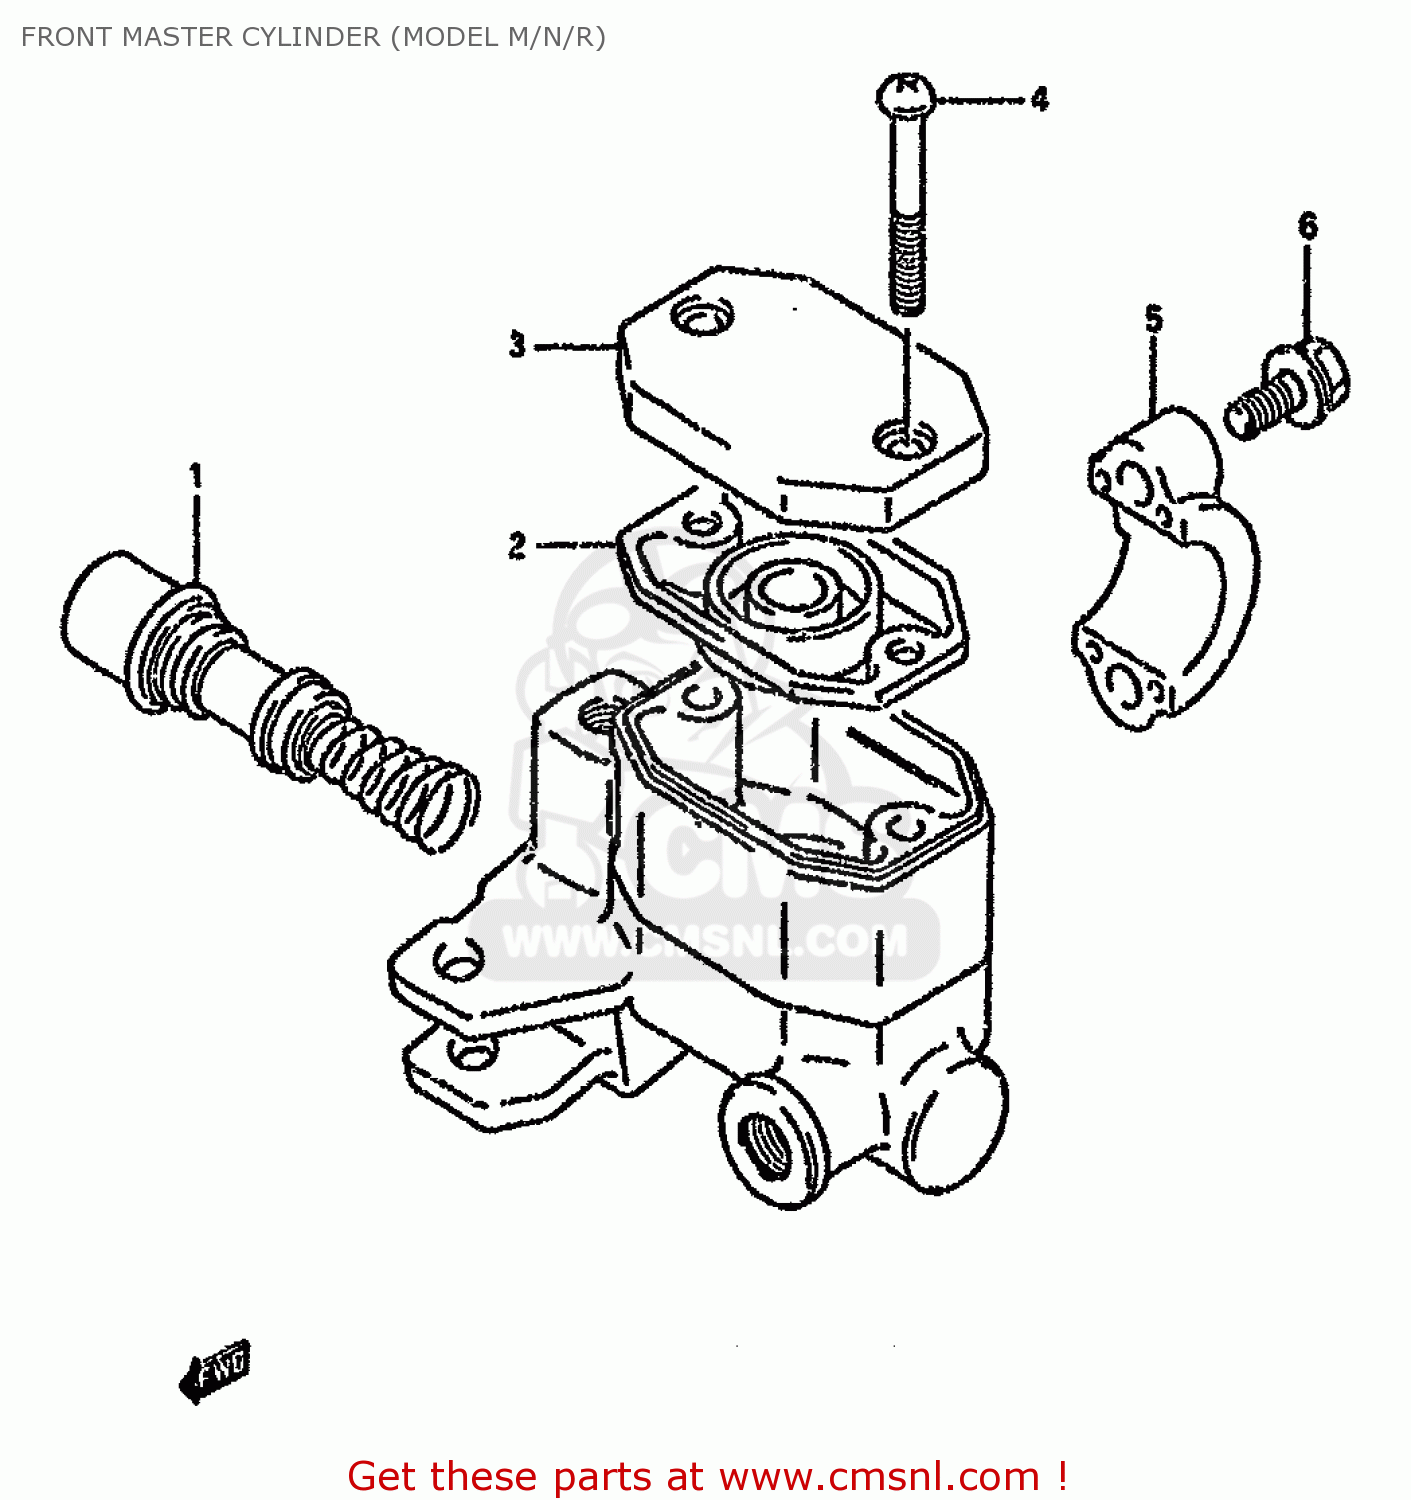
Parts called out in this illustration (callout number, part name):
1	PISTON & CUP SET
2	DIAPHRAGM
3	CAP
4	SCREW
5	HOLDER
6	BOLT
7	HOLDER
8	BOLT
9	WASHER
